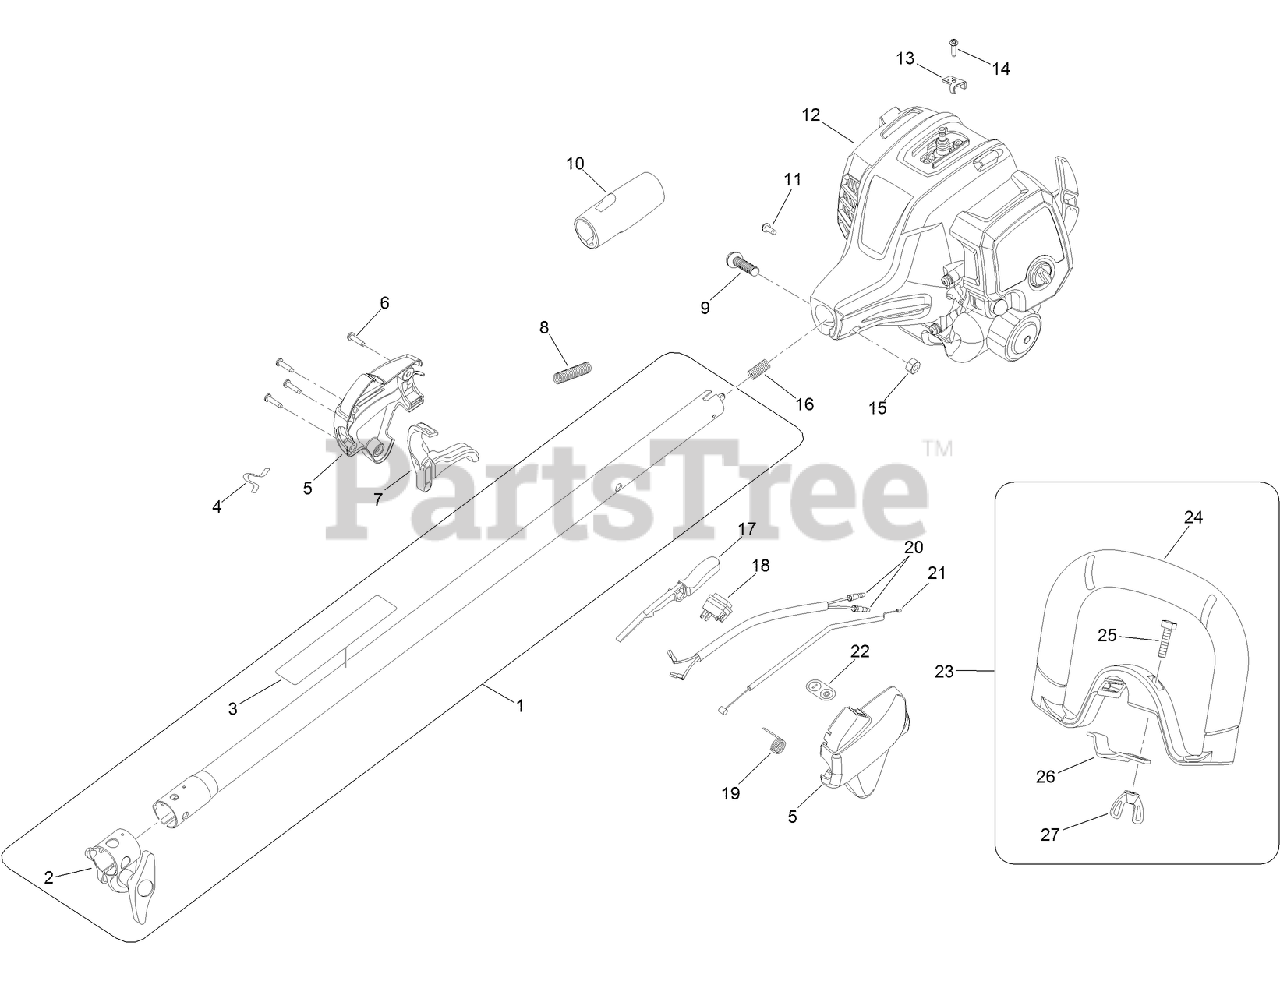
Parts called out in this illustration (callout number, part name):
1	UPPER SHAFT ASM
2	SHAFT CLAMP ASM
3	DECAL-WARNING
4	CLIP-STRAP, SHOULDER
5	CONTROL HANDLE ASM
7	TRIGGER
8	TUBE-CORRUGATED
10	GRIP-SHAFT, UPPER
12	POWERHEAD ASM
13	CLAMP-CABLE, THROTTLE
15	NUT-HEX
16	SPRING-COMPRESSION
17	LOCK-TRIGGER
18	SWITCH-ON/OFF
19	SPRING-TRIGGER
21	CABLE-THROTTLE
22	LABEL-ON/STOP
23	HANDLE ASM
24	HANDLE-SHAFT, UPPER
26	CLAMP-HANDLE, UPPER SHAFT
27	NUT-WING
